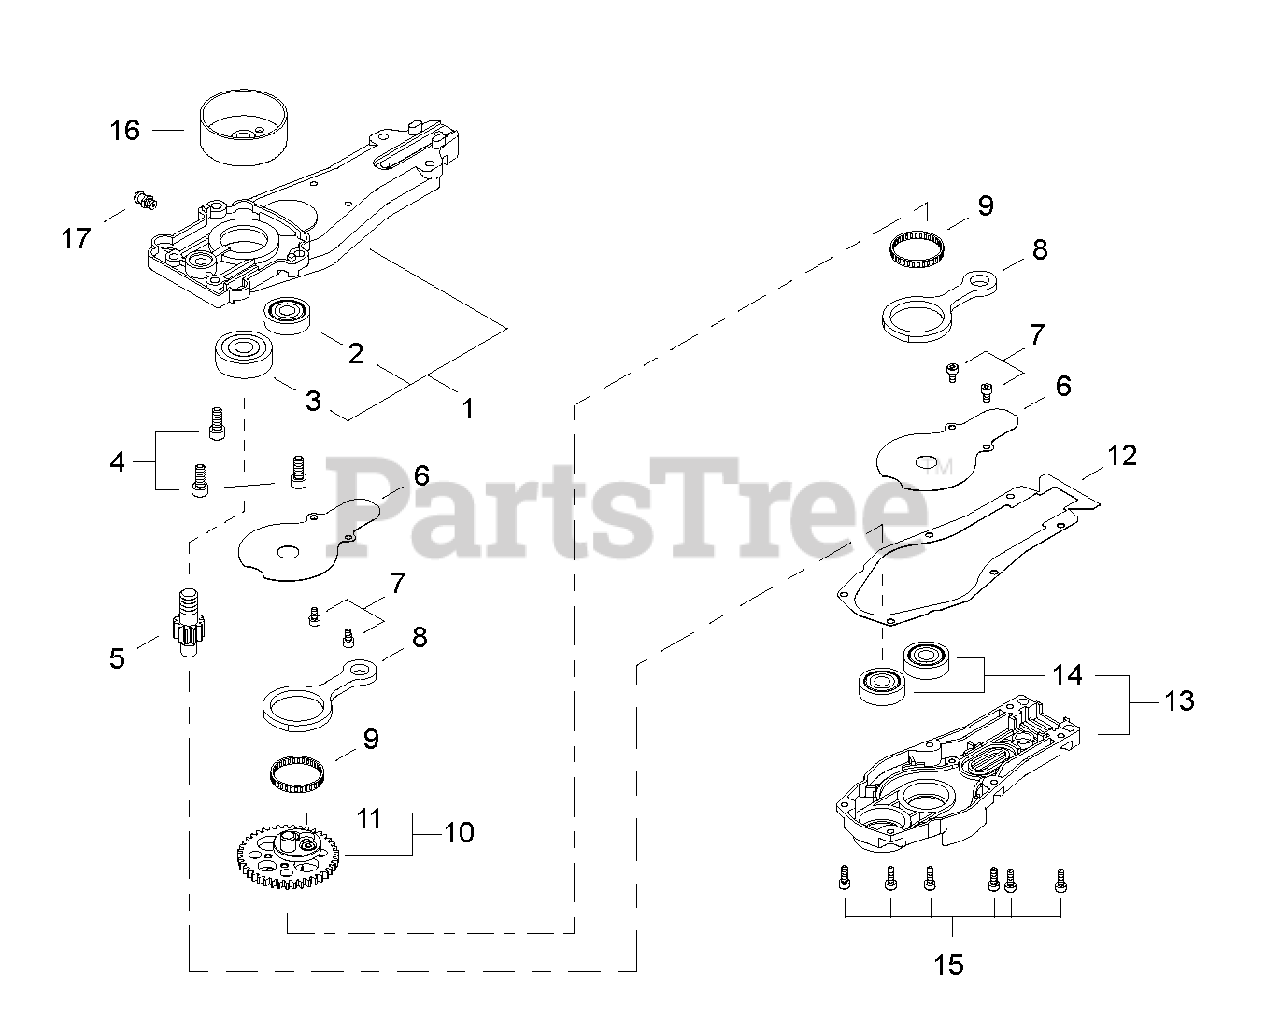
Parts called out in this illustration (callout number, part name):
1	GEAR CASE ASSY
2	BEARING, BALL - 6200ZZ
3	BEARING, BALL - 6301DDU
4	SCREW - 6X16
5	GEAR - PINION
6	PLATE, GEAR CASE
7	SCREW - 4X8
8	ROD, CONNECTING
9	BEARING, NEEDLE - 30
10	CAM GEAR ASSY
11	GEAR - SPUR
12	GASKET, GEAR CASE
13	GEAR CASE COVER ASSY
14	BEARING, BALL - 6200ZZ
15	SCREW - 4X14
16	DRUM, CLUTCH
17	FITTING, GREASE
